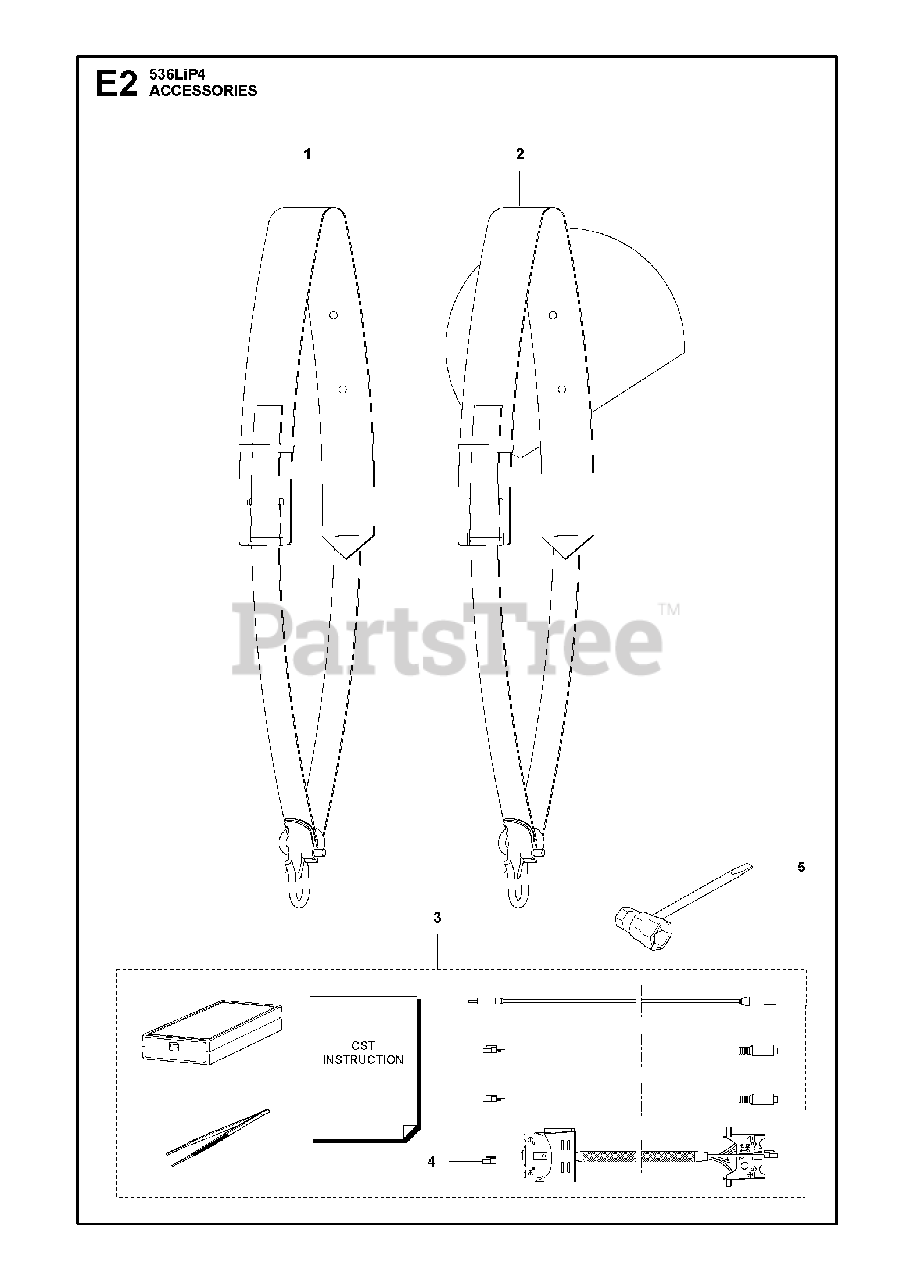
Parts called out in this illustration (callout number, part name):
1	STRAP
2	Shoulder Strap with Sign
3	DIAGNOSTIC TOOL KIT
4	WIRING ASSY
5	COMBI TOOL
